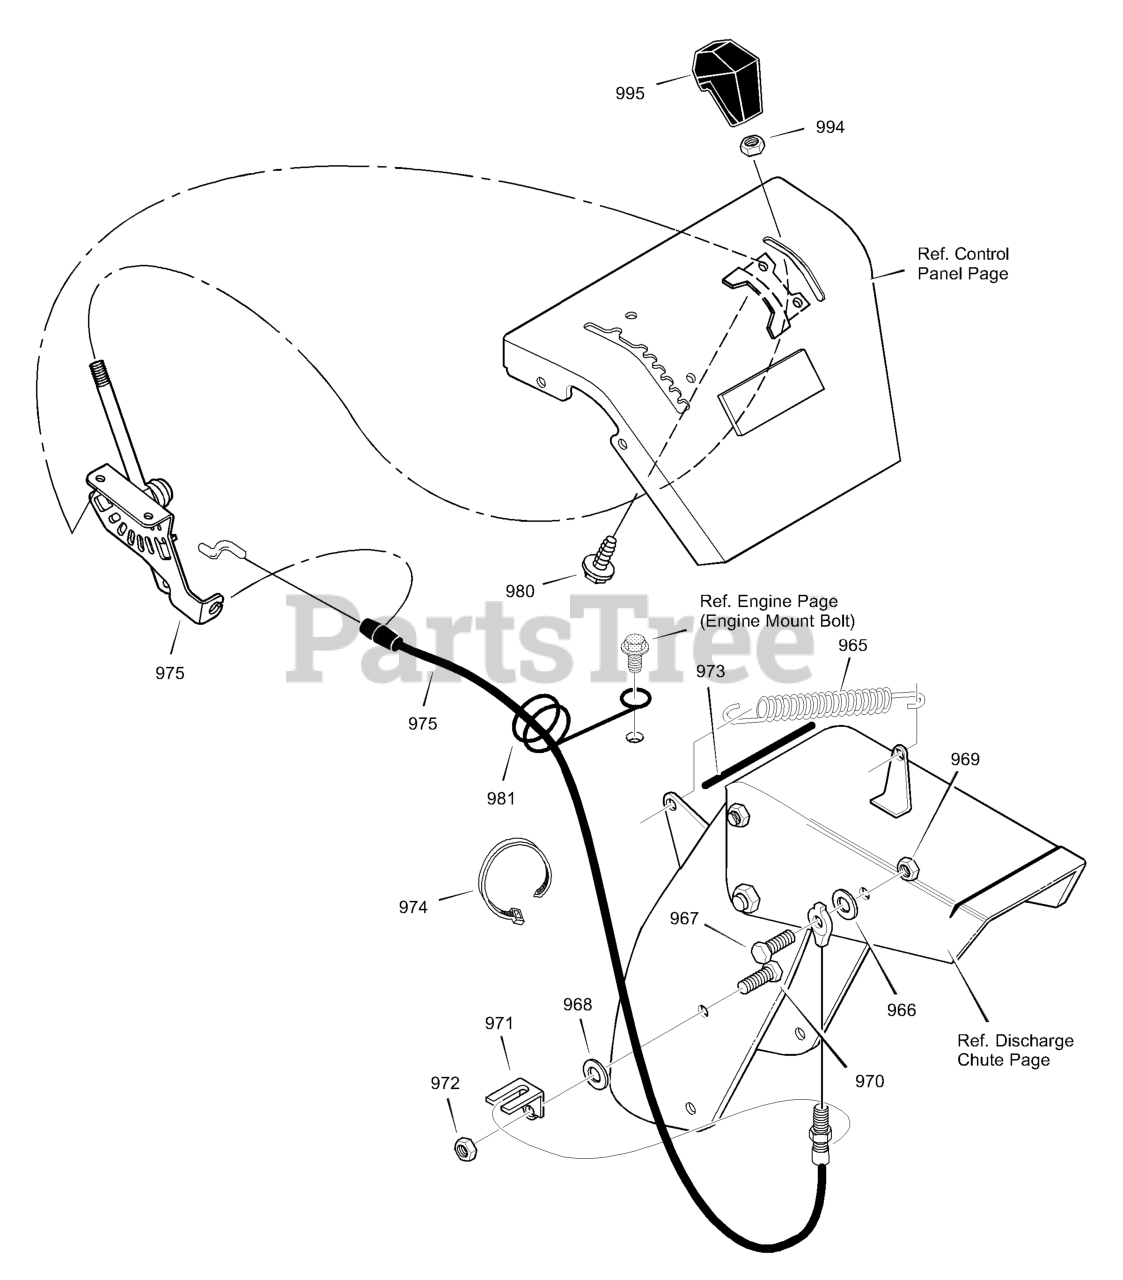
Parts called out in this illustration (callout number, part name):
965	TENSION SPRING
966	FLATWASHER
968	FLATWASHER
969	NUT, 1/4-20 CNTRLK YZ
970	SCREW
971	BRACKET, CABLE CHUTE
972	NUT, 5/16-18 CNTRLK
973	TRIM STRIP, GREY
974	TIE, CABLE
975	ASSY, CHUTE DEF. CONTROL
980	SCREW, 5/16-18 x 0.75
981	WIRE FORM, REMOTE CHUTE CABLE
994	NUT, 3/8-16 JAM
995	KNOB, SHIFT (GREY)
